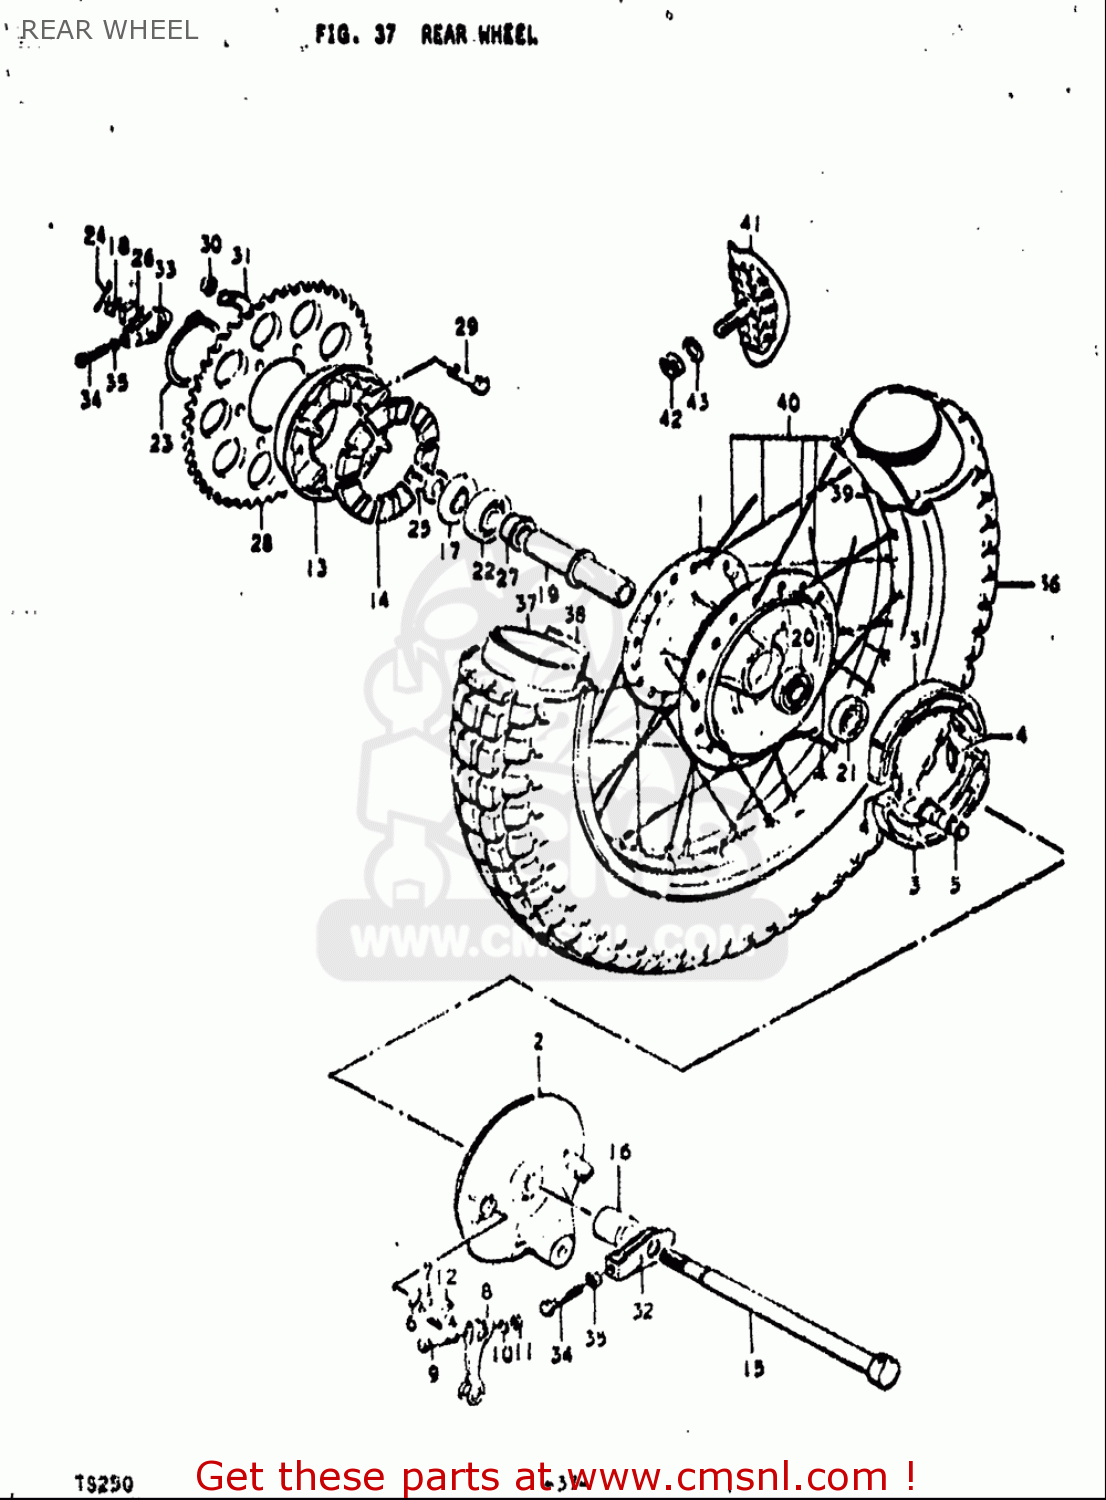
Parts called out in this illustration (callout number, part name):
3	SHOE SET,BRAKE (NAS)
4	SPRING,BRAKE SHOE
6	O RING(D:2.4,ID:14.8)
7	WASHER(15.5X24X1.6)
9	BOLT
10	WASHER
11	NUT
12	SPRING
14	ABSORBER,RR WHEEL HUB SHOCK
15	AXLE,REAR
18	NUT
19	SPACER,REAR HUB BEARING
20	BEARING(15X42X13)
22	BEARING
23	CIRCLIP
24	PIN 30X40
25	SPACER,REAR AXLE,LEFT
26	NUT
27	SPACER,REAR HUB BEARING
28	SPROCKET,RR
29	BOLT(8X33.5)
30	NUT
31	WASHER
32	ADJUSTER,CHAIN,R
33	ADJUSTER,CHAIN,L
34	BOLT(8X50)
35	NUT
37	TUBE,INNER
38	PROTECTOR,INNER TUBE
39	RIM,WHEEL
40	SPOKE SET,RR
41	STOPPER,BEAD(1.85)
43	WASHER
